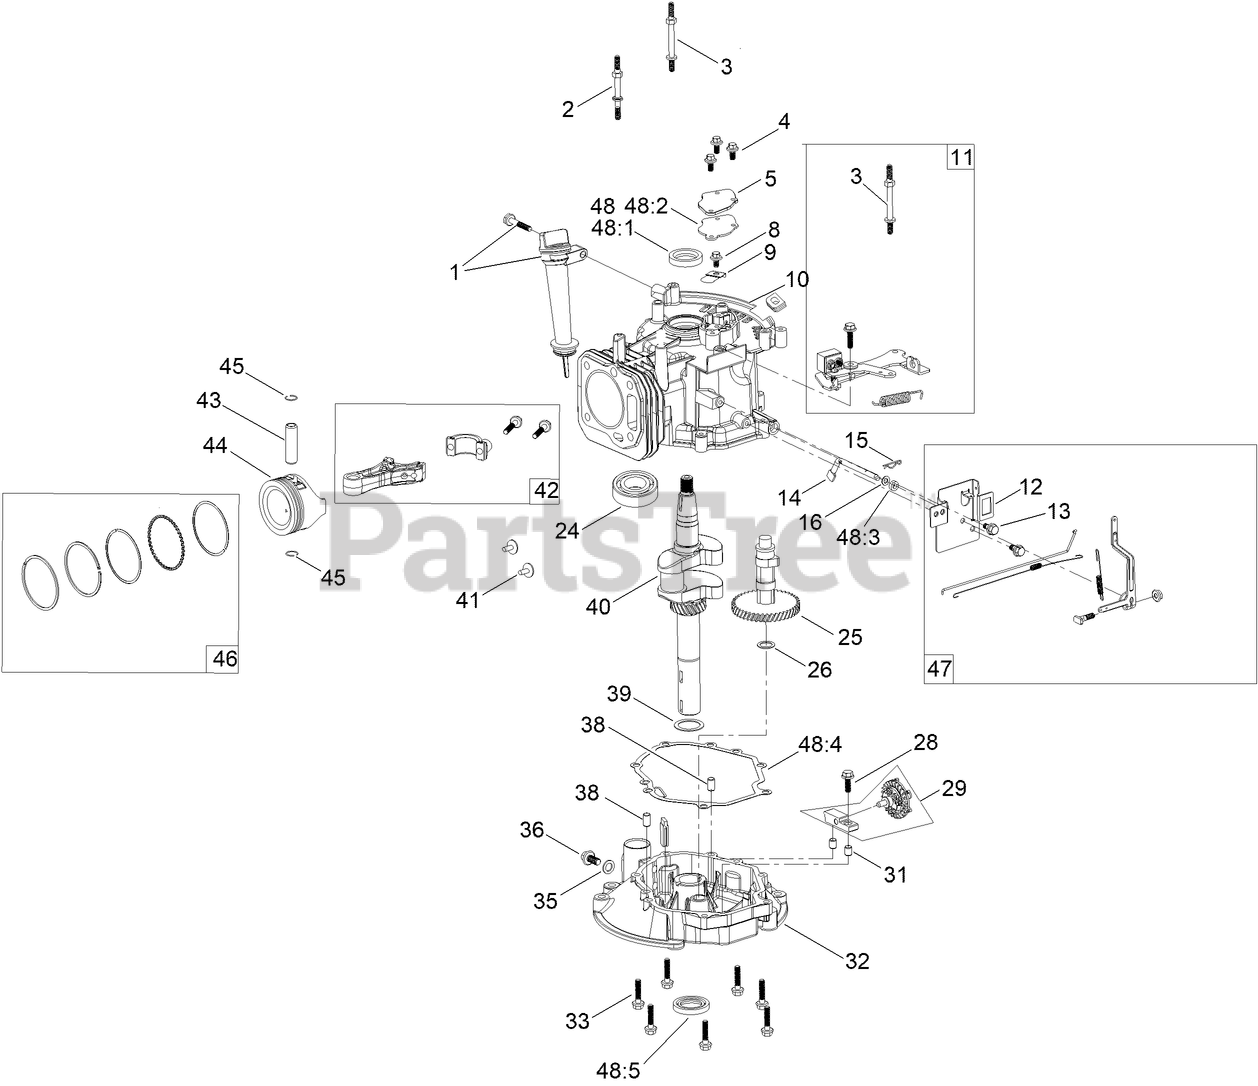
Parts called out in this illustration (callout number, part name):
1	DIPSTICK AND FILL TUBE KIT
2	BOLT-STUD
3	BOLT-STUD
4	SCREW-HHF
5	COVER-PUMP, OIL
8	BOLT-FLANGE
9	VALVE-REED
10	CRANKCASE
11	BRAKE ASM RECOIL KIT
12	CONTROL ASM
13	SCREW-HHF
14	ARM-GOVERNOR
15	PIN-HAIR
16	WASHER-FLAT
24	BEARING-BALL
25	CAMSHAFT ASM
26	WASHER-FLAT
28	BOLT-FLANGE
29	GOVERNOR GEAR ASM
31	PIN-DOWEL
32	COVER-CRANKCASE
33	BOLT-FLANGE
35	WASHER-PLAIN
36	SCREW-HHF
38	PIN-DOWEL
39	WASHER-FLAT
40	CRANKSHAFT ASM
41	TAPPET-VALVE
42	CONNECTING ROD ASM
43	PIN-PISTON
44	PISTON
45	CLIP-PIN, WRIST
46	PISTON RING SET
47	GOVERNOR ARM KIT
48	SEAL AND GASKET KIT
48:1	SEAL-OIL
48:2	GASKET-BREATHER
48:3	SEAL-OIL
48:4	GASKET-COVER, CASE
48:5	SEAL-OIL
